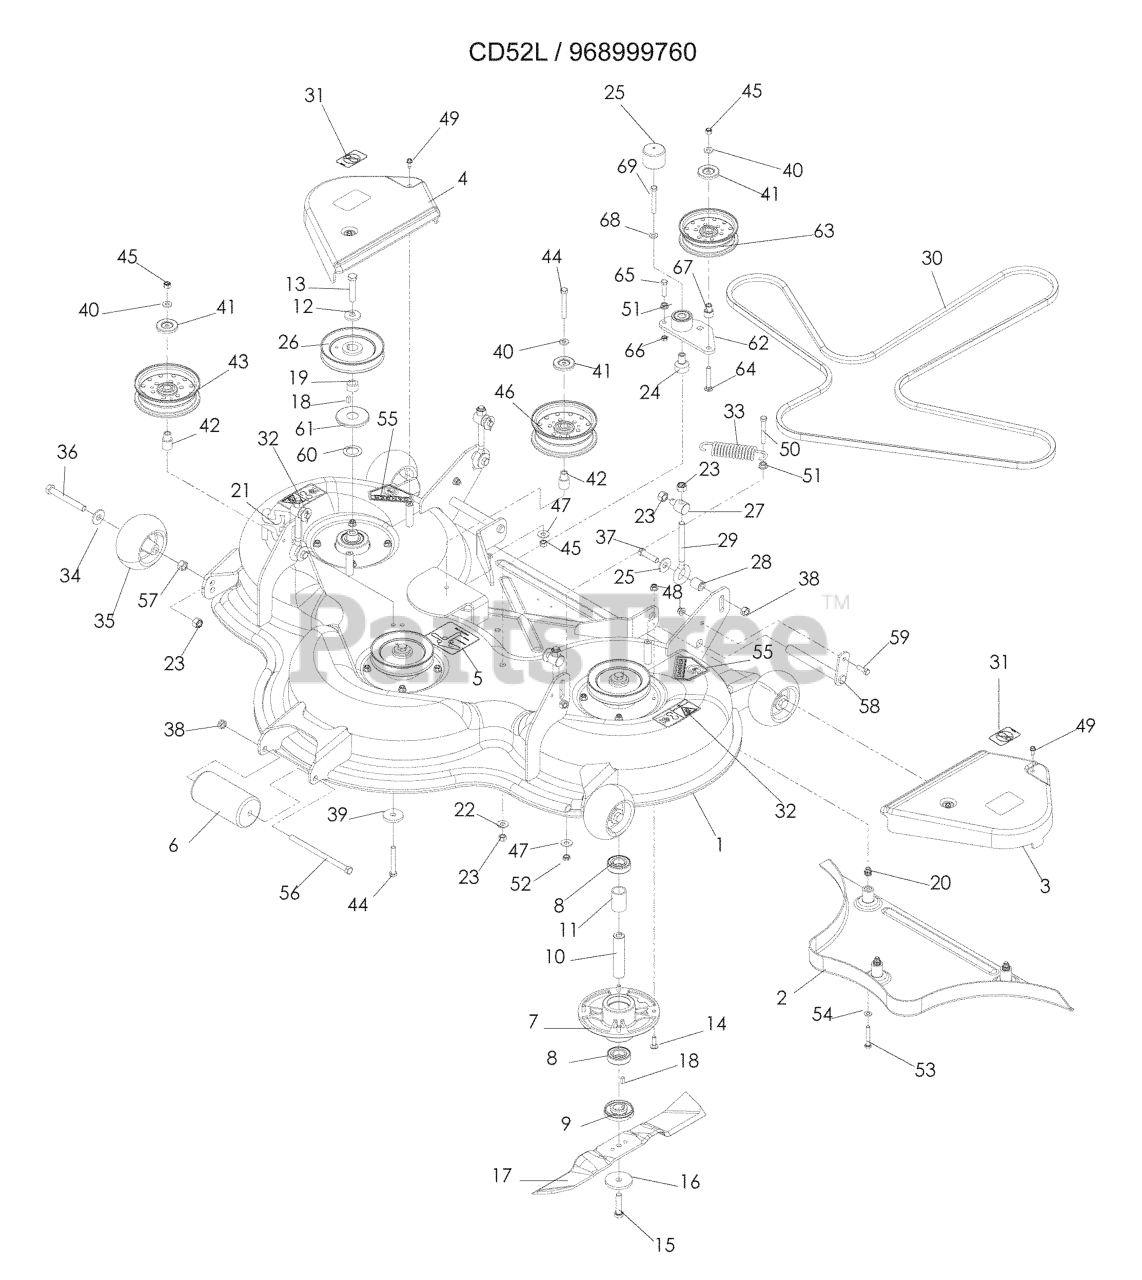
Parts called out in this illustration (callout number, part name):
1	DECK W/DECALS, 52L HUS
3	BELT SHIELD LT
4	BELT SHIELD RT
5	DECAL, BELT ROUTING
6	ROLLER
7	BEARING HOUSING
8	BALL BEARING
9	BUSHING, BLADE
12	WASHER-.533IDX1.37OD
13	HCS M12 X 1.75 X 60 GR5 ZD
14	RHSNB 5/16C X 1
15	HCS M12 X 1.75 X 50 GR8.8 ZD
17	BLADE
19	KEY RETAINER
20	BLIND RIVET NUT
22	WASHER, SUPPORT
23	NUT 1/2-13 HEX NYLOC ZD
24	PIVOT, BEARING
25	CAP, VINYL
26	PULLEY, 52
30	BELT, DECK 52 COMBI/60 GRIZZY
31	DECAL, NO STEP
32	DECAL, BELT DRIVE
34	WASH USS FLAT 1/2
35	GAUGE WHEEL
36	HCS 1/2-13 X 4 GR 5 ZD
37	HCS 7/16 - 14 X 1 3/4
38	NUT 7/16C CENTERLOCK
39	SPINDLE WASHER
40	WASHER, 3/8 THICK
41	DUST SHIELD
42	IDLER BUSHING
43	IDLER PULLEY
44	SCREW 3/8C X 2 3/4 HEX CAP
45	NUT 3/8-16 NYLOC
46	IDLER PULLEY (TALL)
47	WASHER 3/8 FLAT
48	5/16-18 NYLOC FLANGE NUT
49	SCREW 1/4 X 5/8
50	HCS 3/8C X 2
51	NUT 3/8C WHIZ
52	NUT HEX 3/8-16 NYLON, THIN
53	HCS M8 X 1.25 X 50 GR8.8 ZD
54	FLAT WASHER 5/16 SAE
55	DECAL, CPSC
56	HCS 7/16-14 X 7 GR5 ZD
57	NUT HEX 1/2
58	PIN, STRUT, WELDMENT
59	HCS 5/16C X 1
60	WASHER-1.06IDX1.63ODX.06
61	BOTTOM DUST CAP
62	ARM-IDLER W/BRG
63	IDLER PULLEY
64	CARRIAGE BOLT 3/8-16 X
65	HCS 3/8-16 X 1-1/2
66	NUT 3/8-16 HEX JAM
67	BUSHING, IDLER
68	CONTACT BELLSPR 1/2
69	SCREW, 1/2C X 3 HEX CAP
